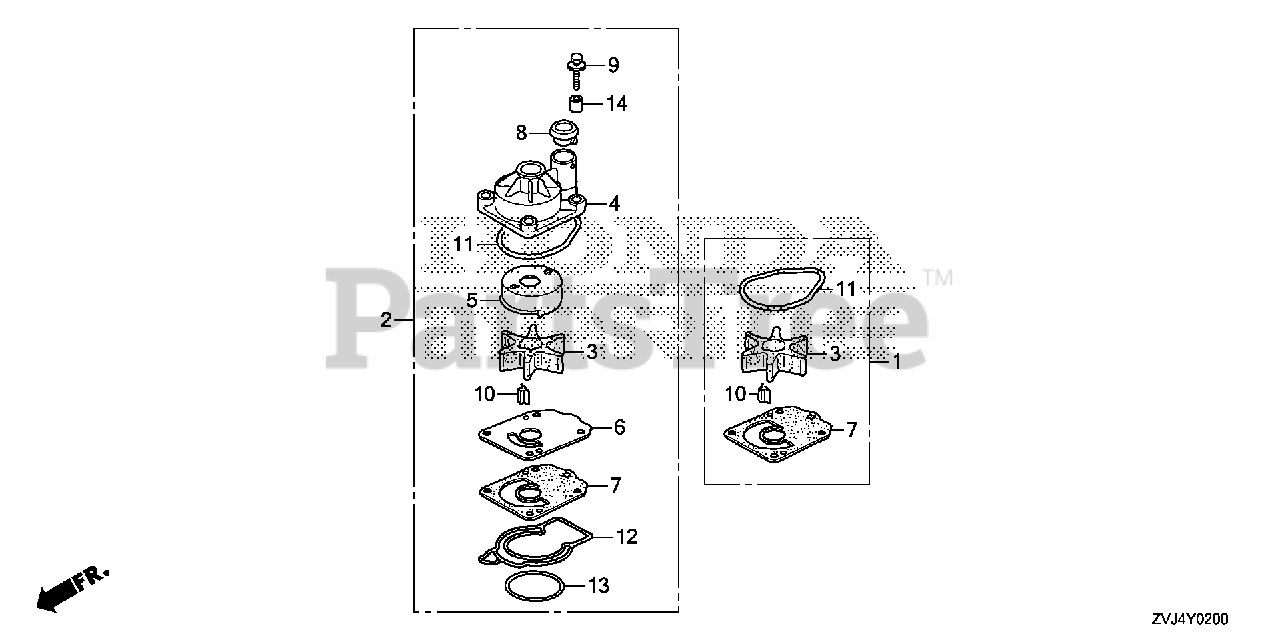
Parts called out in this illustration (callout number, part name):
1	PUMP KIT, IMPELLER
2	PUMP KIT, IMPELLER
3	IMPELLER, PUMP
4	HOUSING, IMPELLER
5	LINER, PUMP
6	COVER, IMPELLER
7	GASKET B, IMPELLER
8	RING, WATER TUBE SEAL
9	BOLT-WASHER (8X60)
10	KEY, WOODRUFF
11	O-RING, WATER PUMP
12	O-RING, WATER PUMP HOUSING
13	O-RING (65.4X2.4)
14	COLLAR, DISTANCE
